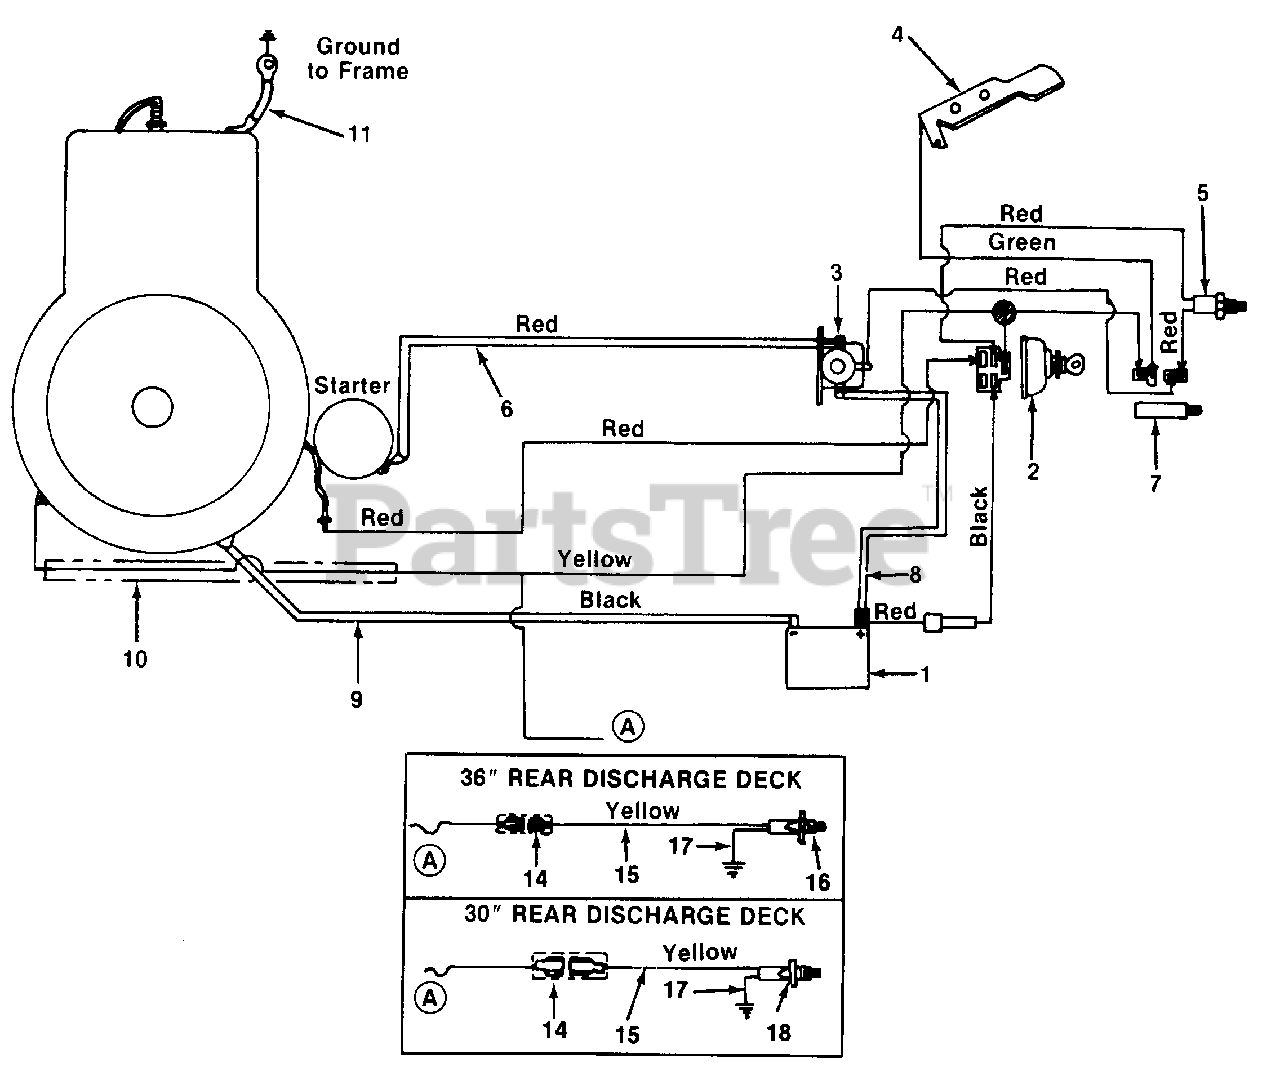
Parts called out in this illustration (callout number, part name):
1	BATTERY
2	SWITCH-IGNITION
3	SOLENOID
4	SPRING-SWITCH
5	SWITCH
7	SWITCH-SAFETY
8	WIRE W/BOOT
10	CONDUIT-CONVOLUTED
14	RECEPTACLE-INSULATED TAB
17	WIRE-REV LOCKOUT
18	SWITCH-SAFETY
